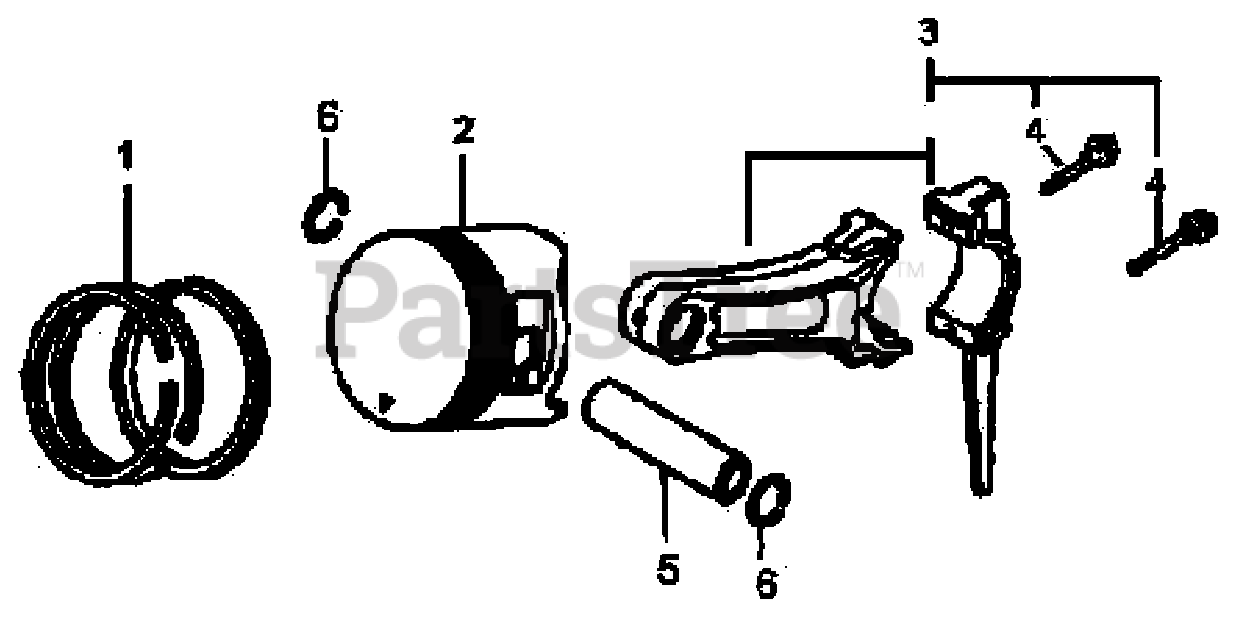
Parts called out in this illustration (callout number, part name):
1	RING SET, PISTON
3	CONNECTING ROD ASSY.
4	BOLT, CONNECTING ROD
5	PIN, PISTON
6	CLIP, PISTON PIN
